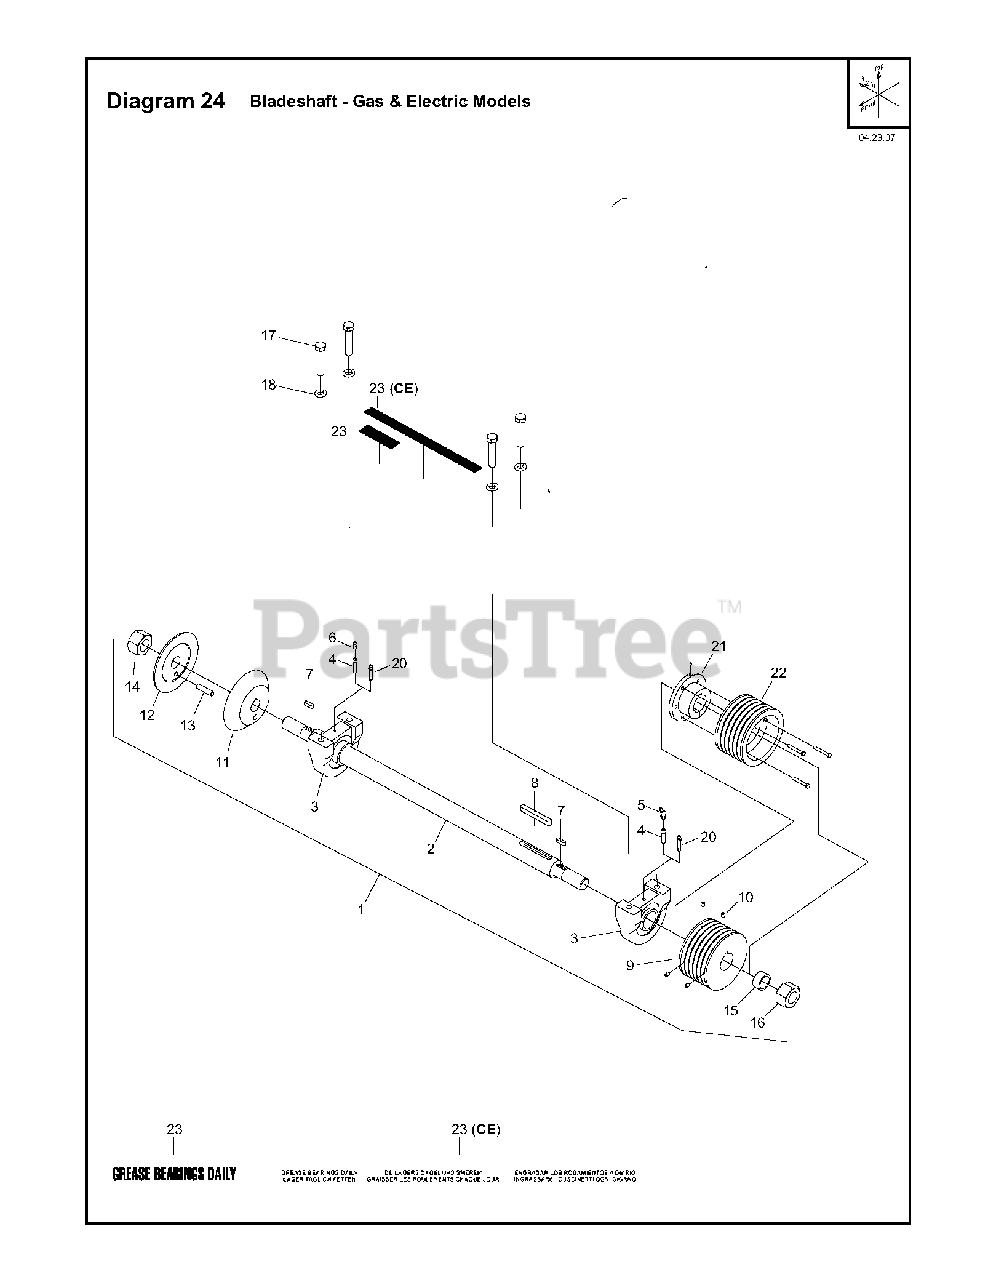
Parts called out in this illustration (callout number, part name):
1	BLADE SHAFT ASSY: 18-26" B/M
3	BEARING: BALL 1.438"
4	GREASE
5	GREASE FITTING
7	KEY. ROUND END .25 X .843
8	KEY. SQ. RND END 3/8 x 2.75LG
10	SHSS. .25-20 x .375 CUP HK
12	COLLAR. OUTER - 5" OD
15	THREAD PROTECTOR SLEEVE
17	HHCS. .5-13 x 2.5 GR 5 Z/P
18	LOCKWASHER. SPLIT .5 Z/P
20	ETL RALLY REOX582TF/98
21	BOLT.SHOULDER *SUBS/2*
